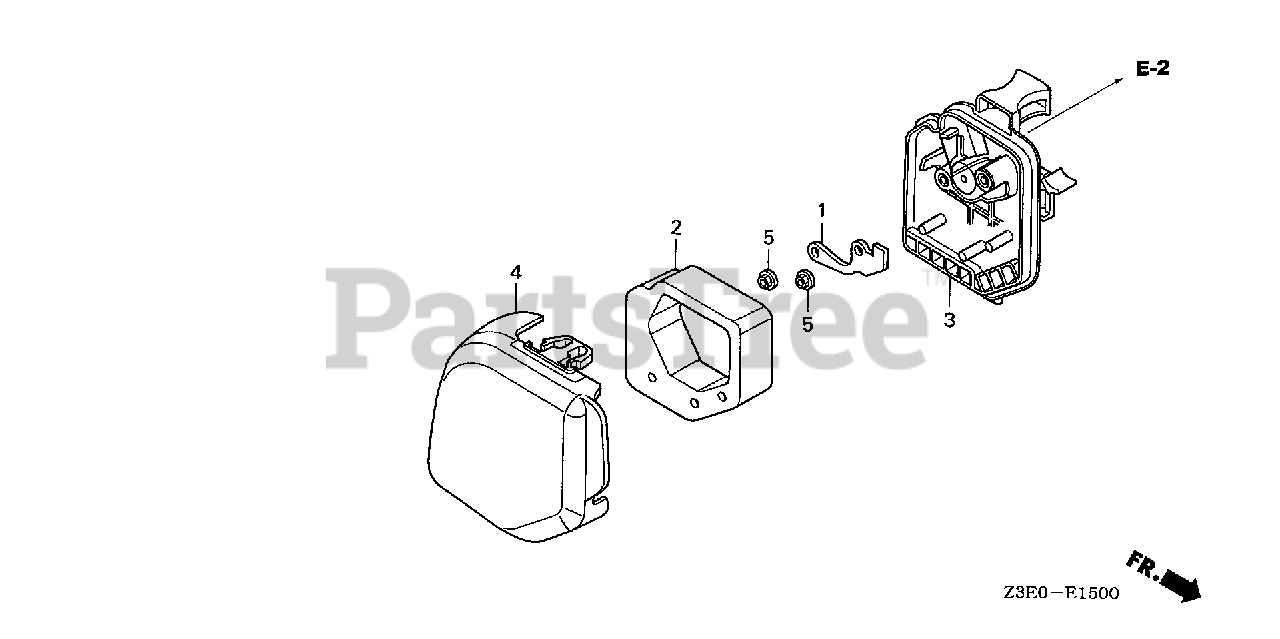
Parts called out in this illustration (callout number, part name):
1	PLATE, OIL TRAP
2	ELEMENT, AIR CLEANER (SEMI-DRY)(HUSQVARNA ONLY)
3	HOUSING, AIR CLEANER *T93* (HUSQVARNA ONLY) (HUSQVARNA GRAY)
4	COVER, AIR CLEANER *T93* (HUSQVARNA ONLY) (HUSQVARNA GRAY)
5	NUT, FLANGE (5MM)
